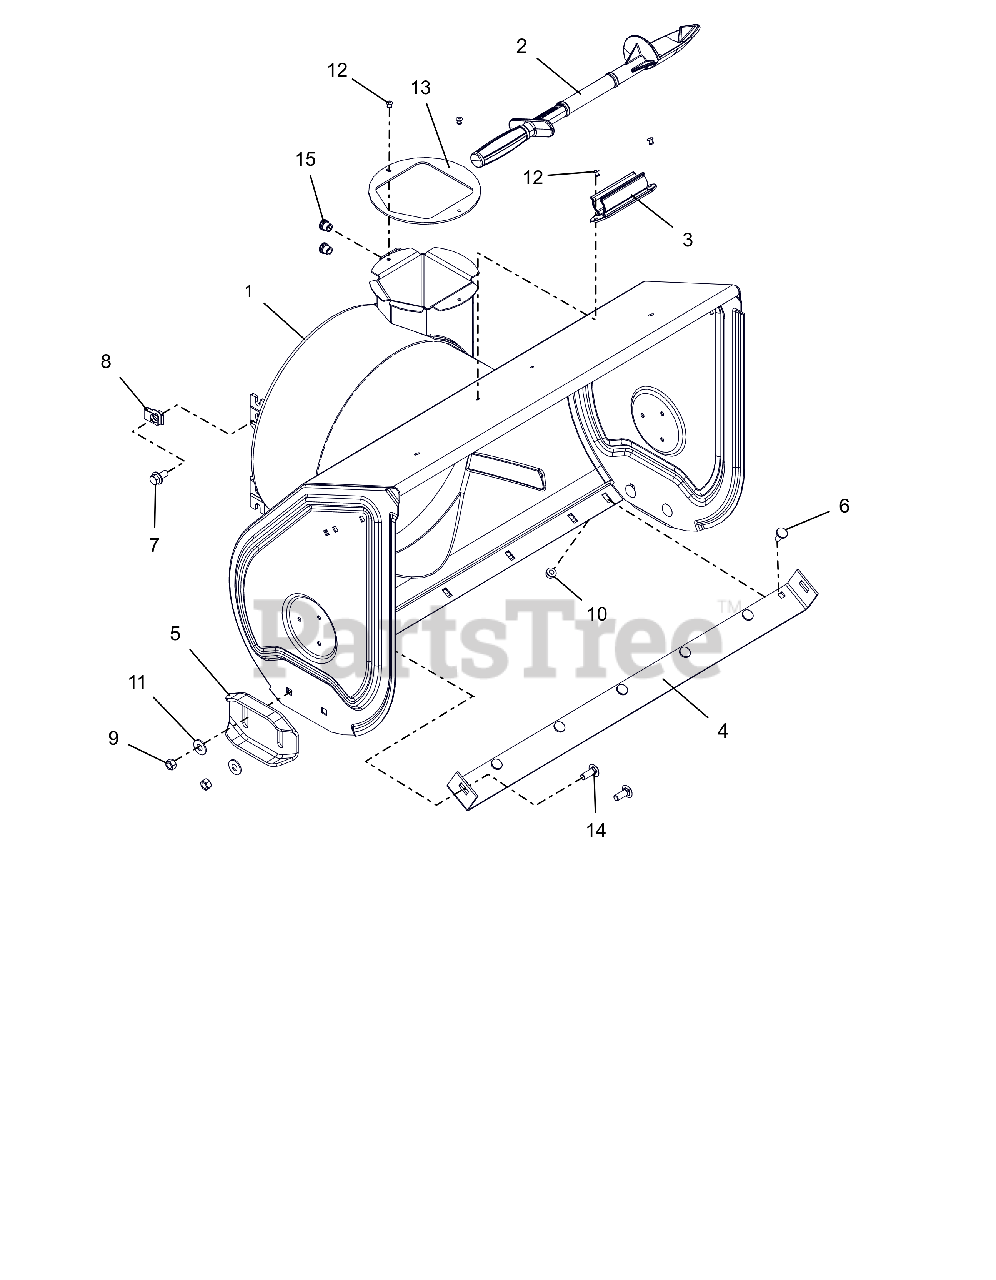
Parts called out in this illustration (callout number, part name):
1	BLOWER HOUSING W/DECAL 30"
2	DEVICE, SNOW CLEAN OUT
3	MOUNT, SNOW CLEAN OUT
4	BLADE, SCRAPER-30"
5	SKID SHOE, REVERSIBLE - ORANGE
6	BOLT, MODIFIED HEAD CARRIAGE
8	NUT-RTNR .375-16X.37
9	NUT-LK-CTR .38-16 ZC120
10	NUT-LK-TOP-FLG .312-18 GF ZCC
11	WSHR,FLT .438X1.00X.083 ZCC
12	RVT, POP .1875 ZCC
13	BAFFLE, DISCHARGE NECK
14	BLT,RHSSN .38-16X1.00 G5 ZCC
15	NUT,THD,INSERT .38-16 ZC120
